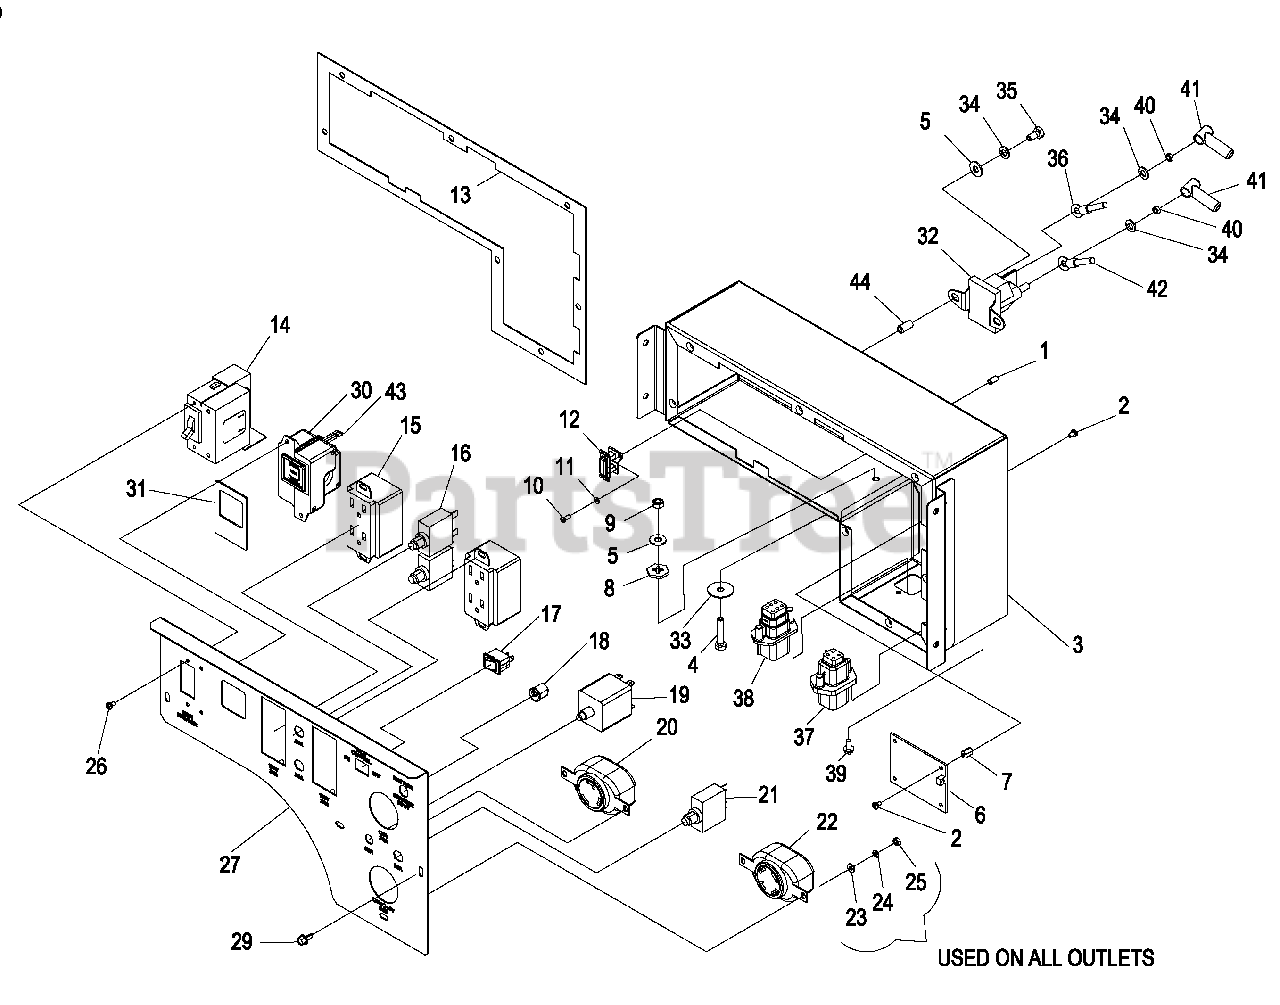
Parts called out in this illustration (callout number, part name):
1	NUT TRIC M3 X .5
2	SCREW PPHM #6-32 X 1/4 SEMS
3	CONTROL PANEL 8KW ENCL PORTABLE
4	SCREW HHC M6-1.0 X 30 C8.8 FT
5	WASHER FLAT 1/4-M6 ZINC
6	ASSEMBLY PCB PORTABLE SYSTEM CONTROL
7	HEX STAND-OFF #6-32 X 3/8"
8	WASHER LOCK SPECIAL 1/4"
9	NUT HEX M6 X 1.0 G8 YEL CHR
10	SCREW PPHM M3-0.5 X 8
11	WASHER LOCK M3
12	TRANSFORMER, IDLE CURRENT PORTABLE
13	GASKET PORTABLE CONTROL PANEL
14	CIRCUIT BREAKER, 2-P 35A W/SHUNT TRIP (AIRPAX PART NUMBER: LEL12-1REC5-36494-35-G1-V)
15	OUTLET 20A 120V DPLX
16	CIRCT BRK 20X1 UL/CSA
17	SWITCH, MOMENTARY (OFF) - ON
18	12VDC POWER JACK
19	CIRCUIT BREAKER 30A 2P PUSH TO RESET (AIRPAX PART NUMBER: PR21-2-30.OA-XX)
20	OUTLET 30A 120V RECEPT
21	CIRCT BRK 30X1 UL/CSA
22	RECEPTACLE 30A 125/250V L1430R
23	WASHER, FLAT, M4
24	WASHER LOCK #8-M4
25	NUT HEX M4-0.7 G8 YEL CHR
26	SCREW PPHM #6-32 X 1/4 SEMS, BLACK OXIDE W/OIL
27	410 CONTROL PANEL COVER
29	SCREW HHTT M5-0.8 x 1.0
30	GFCI SENSING MODULE ASSEMBLY
31	GASKET GFCI
32	CONTACTOR, STARTER SOLENOID
33	WASHER FLAT 0.25ID X 1"OD ZINC
34	WASHER LOCK M6-1/4
35	SCREW HHC M6-1.0 X 12 G8.8
36	WIRE, #16 START SOL-STARTER
39	SCREW PLASTITE HI-LOW #10 X 3/8
40	NUT HEX 1/4-20 STEEL
41	BOOT, BATTERY CABLE
42	WIRE, STARTER SOL-BATTERY
43	WIRE, JUMPER GFCI
44	NUT, TRIC M6-1.0
